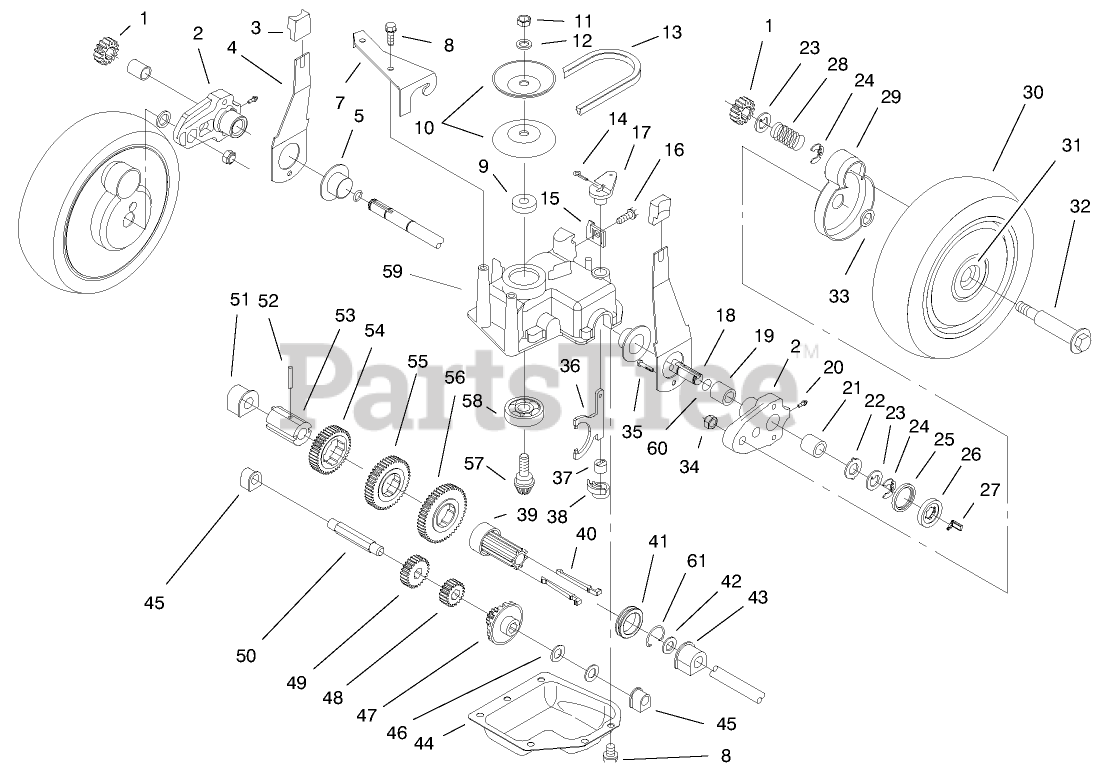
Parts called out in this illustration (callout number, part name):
1	GEAR-PINION
3	KNOB-ARM
4	SPRING ARM ASM
5	CAP-END
8	SCREW-HWHTF
9	SPACER
11	NUT-HEX
12	WASHER-FLAT
13	V-BELT
14	PIN-COTTER
15	CLAMP-CABLE
16	SCREW-HWHTF
17	LEVER-SHIFT
18	SHAFT-OUTPUT
19	BUSHING
20	FITTING-GREASE
22	WASHER-ARM, PIVOT
23	WASHER-THRUST, KEYED
24	RING-RETAINING,CLIP
25	RING-FRICTION
26	WASHER-CLUTCH
27	KEY-ROCKING, LH
28	SPRING-COMPRESSION
29	COVER-WHEEL
30	WHEEL AND TIRE ASM
31	BUSHING
33	SPACER-COVER, WHEEL
34	NUT-LOCK
35	SCREW-HWH
36	YOKE-SHIFT
37	BUSHING-YOKE
38	RETAINER-FORK, SHIFT
39	SLEEVE-KEY, SHIFT
40	KEY-SHIFT
41	COLLAR-SHIFT
42	WASHER-PLAIN
43	BUSHING-OUTPUT
45	BUSHING
46	WASHER-THRUST
48	PINION-20T
49	PINION-25T
51	BUSHING
52	PIN-SPRING
53	SLEEVE-GEAR
54	GEAR-39T
55	GEAR-44T
56	GEAR-49T
58	BEARING-BALL
59	CASE-GEAR, UPPER
60	O-RING
61	CLIP-SPRING
